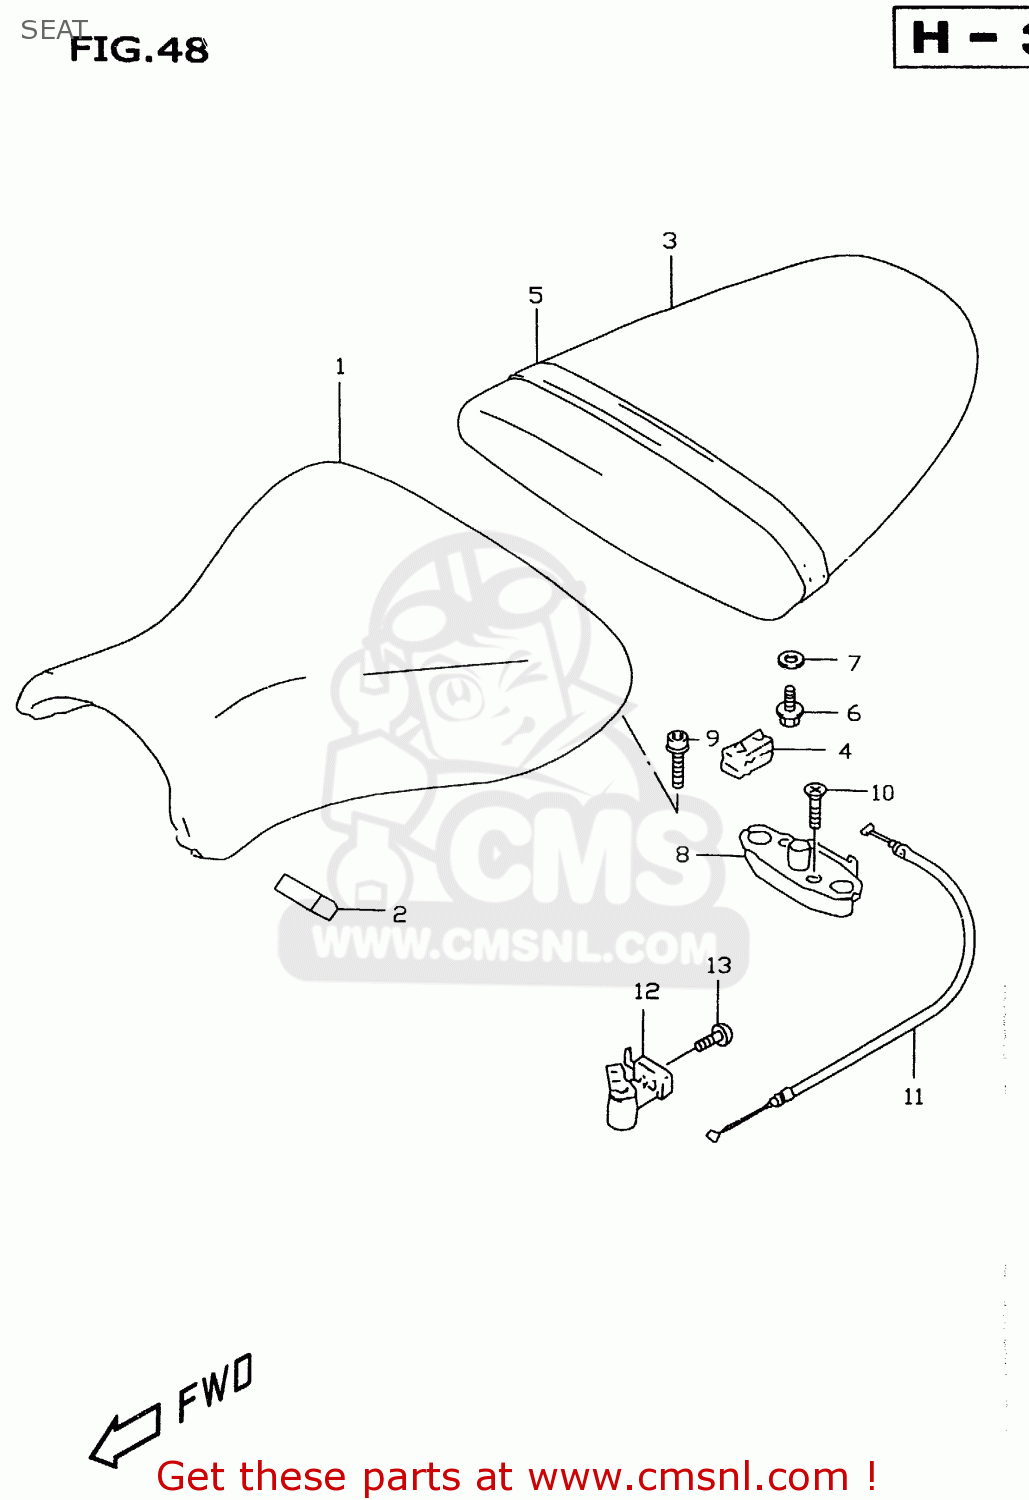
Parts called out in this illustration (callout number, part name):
1	SEAT ASSY(BLACK)
2	CUSHION,FR(20X40X15)
3	SEAT ASSY,PILLION
4	CUSHION,SEAT(40X20X15)
5	BAND,SEAT
6	BOLT
7	WASHER(6.5X20X1.6)
8	BRACKET,SEAT SUPPORT,RIGHT
9	BOLT(6X18)
10	SCREW
11	CABLE,SEAT LOCK
12	LOCK SET,SEAT
13	SCREW
